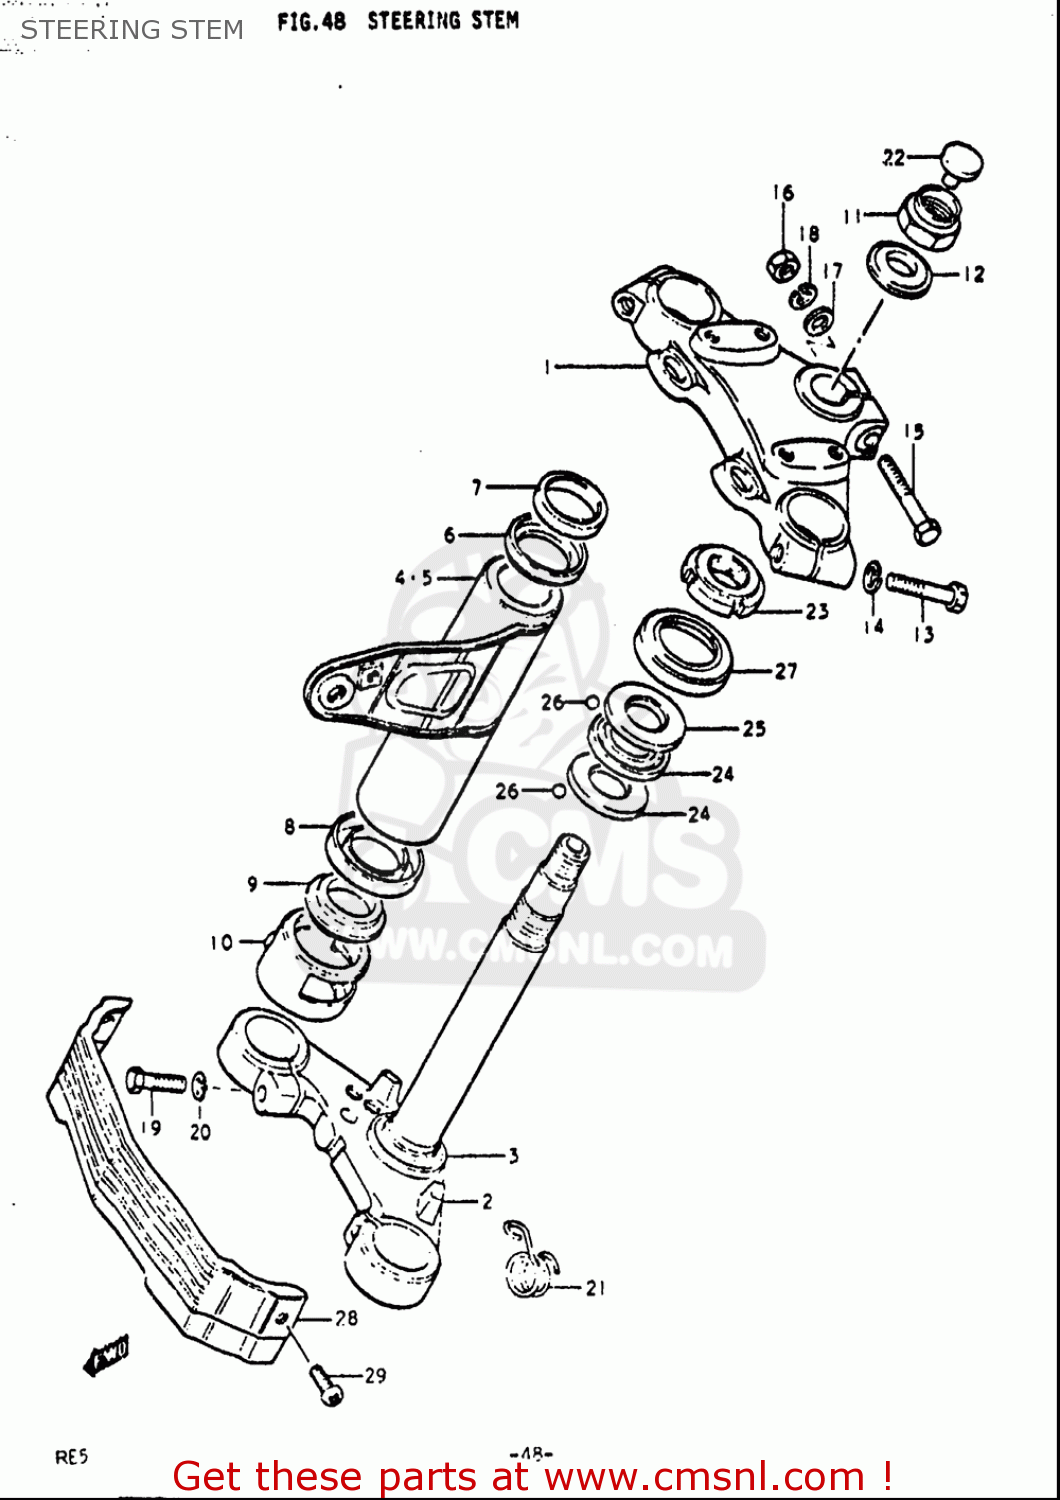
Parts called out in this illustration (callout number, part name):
3	RACE,STEERING OUTER LWR
6	GUIDE
7	CUSHION,HEADLAMP BRACKET UPR
8	GUIDE
9	CUSHION,HEADLAMP BRACKET
10	COVER,FORK LWR BRACKET
11	NUT
12	WASHER
13	BOLT
14	WASHER,LOCK
15	BOLT
16	NUT
17	WASHER
18	WASHER,LOCK
19	BOLT
20	WASHER,LOCK
22	CAP(OD:20)
23	NUT,STEERING STEM(25X44X10)
24	LACE,STEERING INNER LWR
25	LACE,STEERING OUTER UPR
26	BALL
27	DUST SEAL,STEERING UPR
29	SCREW(5X6)
